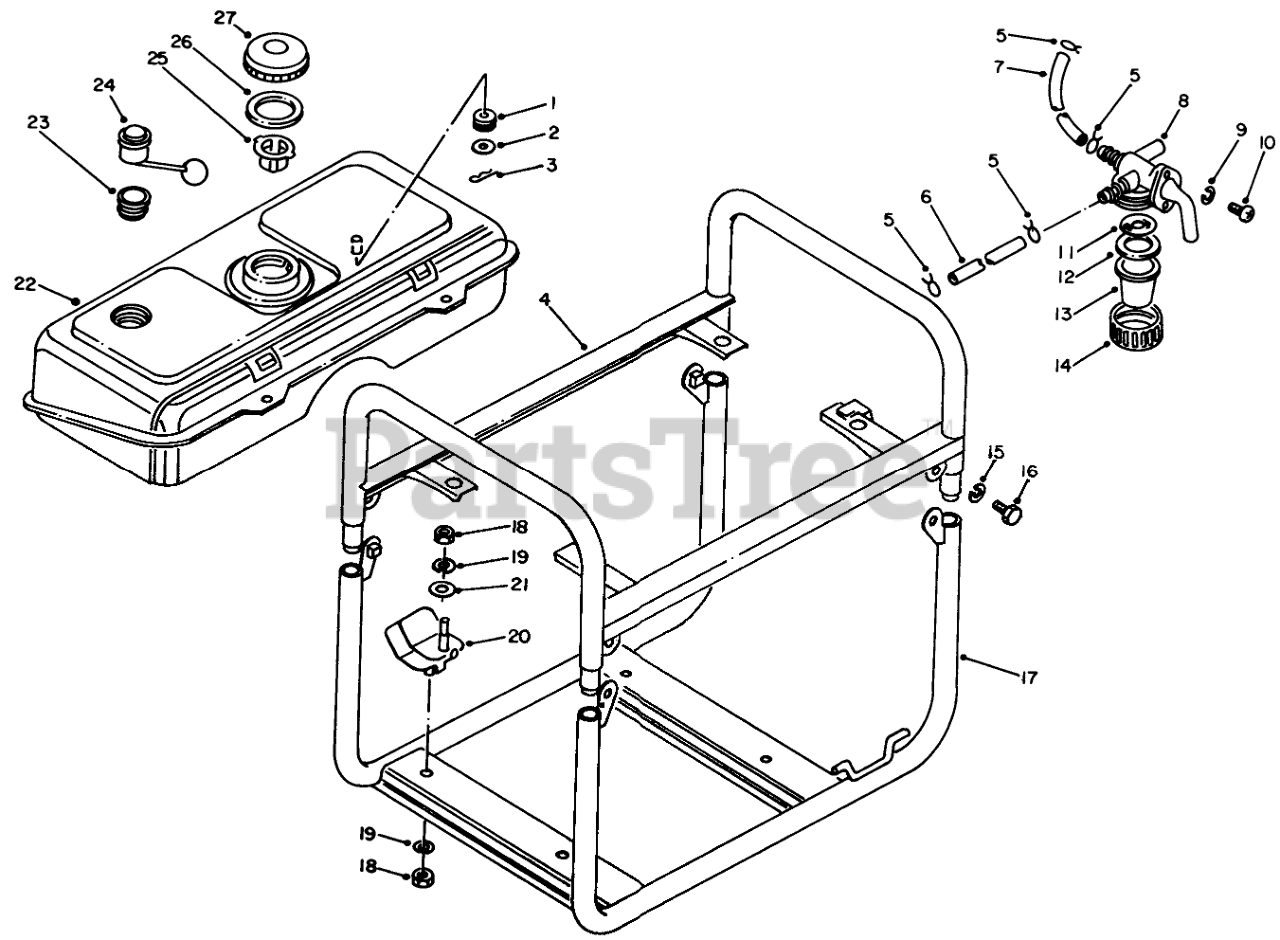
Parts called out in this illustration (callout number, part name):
1	CUSHION
2	WASHER
4	Upper Frame
8	Cock Assembly (Incl. Ref. #11-14)
9	Lockwasher
10	Screw
11	FILTER
12	GASKET
15	Lockwasher
17	Lower Frame
18	Nut
19	WASHER-LOCK
20	Engine Mount
21	Washer
22	Fuel Tank
23	Gasket
24	Fuel Gauge Assembly (Incl. Ref. #23)
25	Filter
26	GASKET
